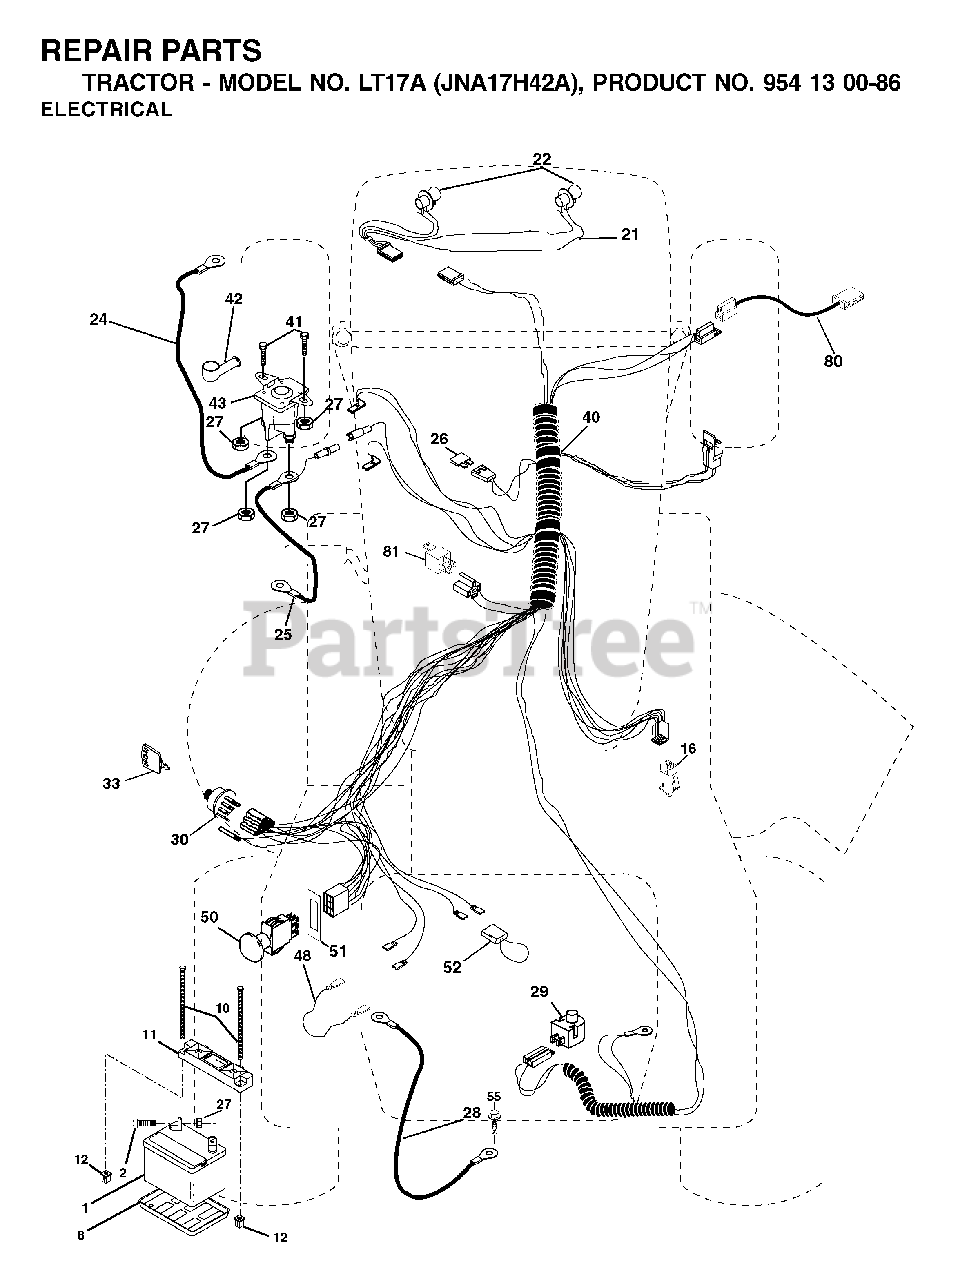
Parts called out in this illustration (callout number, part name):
1	REPL BY 532 12 38-99
8	BATTERY TRAY T
10	BOLT 1/4-20 X 7.5
11	BATTERY HOLDDOWN
12	NUT, PUSH NYLON 1/4" BATTERY
16	SWITCH INTERLOOK PUSH-IN
21	WIRE HARNESS
22	LIGHTBULB
24	CABLE BATTERY 6 GA 22" W/16W
25	BATTERY CABLE GT
26	FUSE 20AMP
27	NUT
28	CABLE GROUND 6 GA 21" 90T BLK
29	PLUNGER SWITCH (COLOR:OLIVE)
30	IGNITION SWITCH
33	KEY MLD GEN DELTA
40	IGNITION HARNESS
42	TERMINAL COVER
43	SOLENOID
50	PTO SWITCH
51	RETAINING RING
52	WIRE PROTECTION LOOP
80	HARNESS, CLUTCH
81	RELAY.ASSY.T
